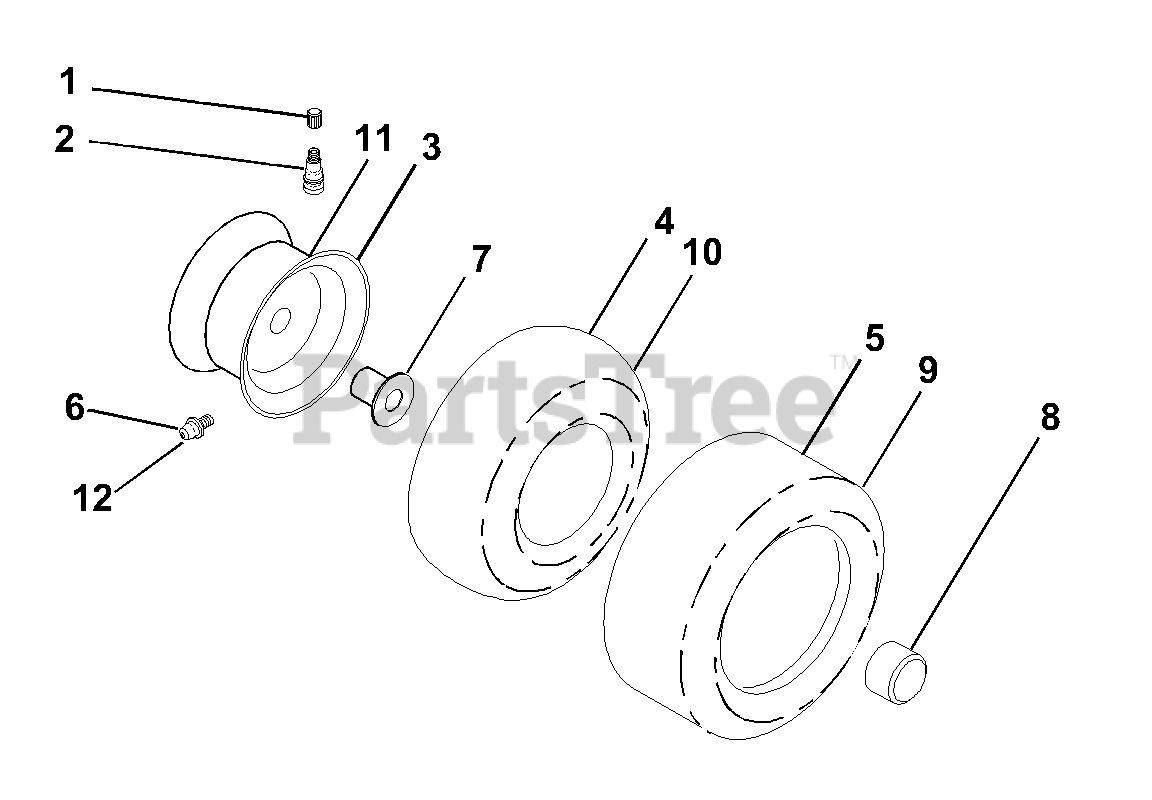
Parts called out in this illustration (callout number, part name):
1	Cap, Valve, Tire
2	Stem, Valve
3	Rim Assembly, Front
4	Tube, Front
5	Tire, Front
6	Fitting, Grease
7	Bearing, Flange
8	Cap, Axle
9	Tire, Rear
10	Tube, Rear
11	Rim Assembly, Rear
12	Fitting, Grease
